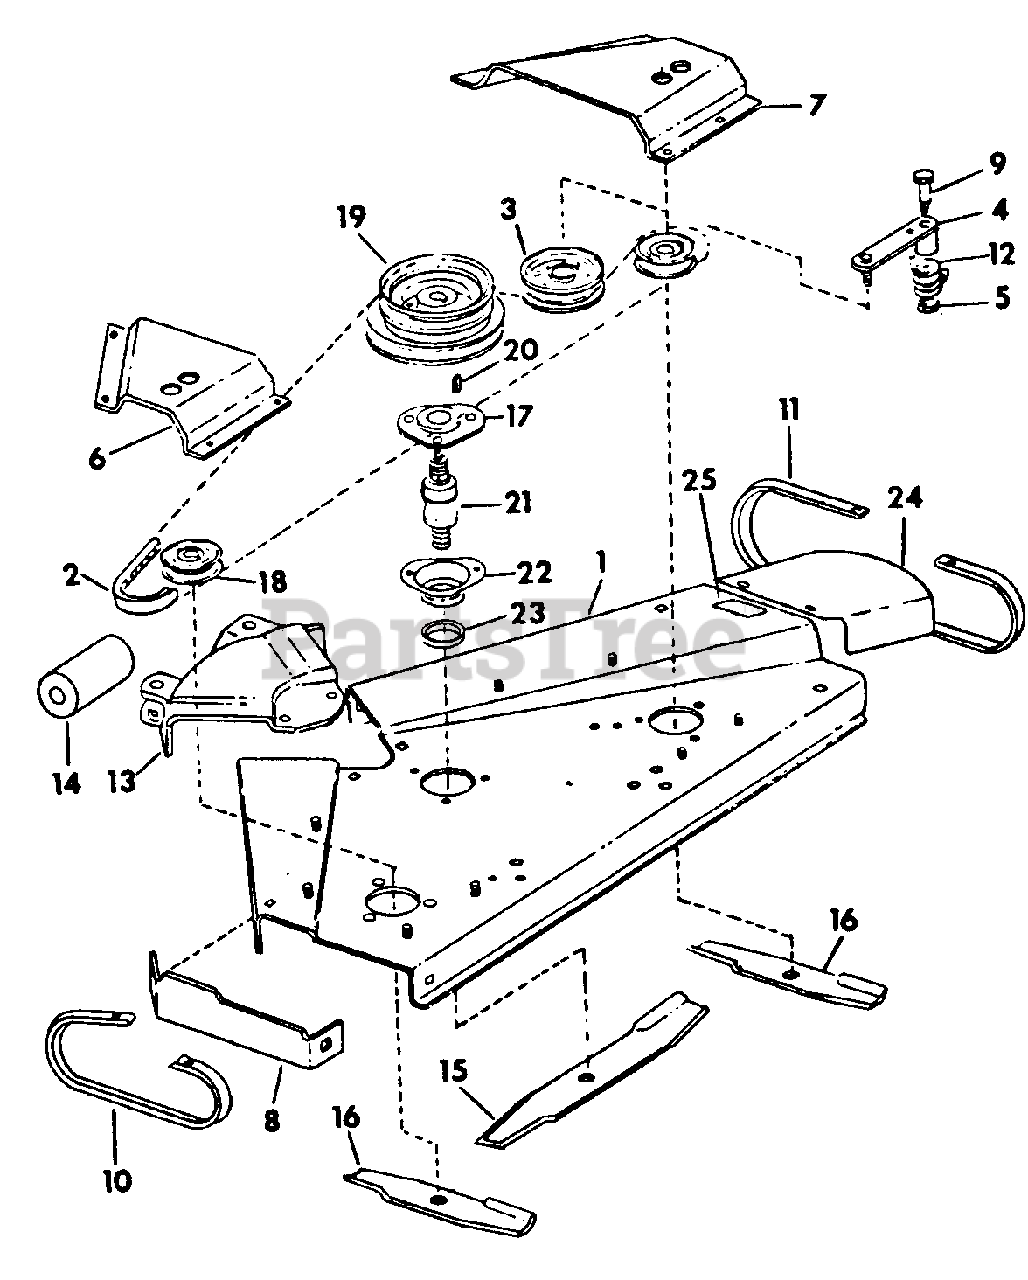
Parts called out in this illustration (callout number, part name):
1	Housing Assy w/Product Graphic, Rotor
2	Belt, Spindle Drive -38 In. Blade
3	Pulley, Flat Idler
4	Arm Assy, Idler
5	Nut, Center Lock
6	Shield, Belt LH
7	Shield, Belt RH
8	Side, Housing LH
9	Bolt, Idler Arm Pivot
10	Runner, Mower LH
11	Runner, Mower RH
12	Spring, Torsion
13	Housing, Center
14	Roller, Front
15	Blade, Center -Hard Surfaced
16	Blade, Outer -Hard Surfaced
17	Cap, Spindle Housing
18	Pulley, Outer
19	Pulley, Center
20	Key, 1/4 X 3/4 Woodruff
21	Bearing, Ball
22	Housing, Spindle
23	Cup, Spindle
25	Product Graphic, Caution
